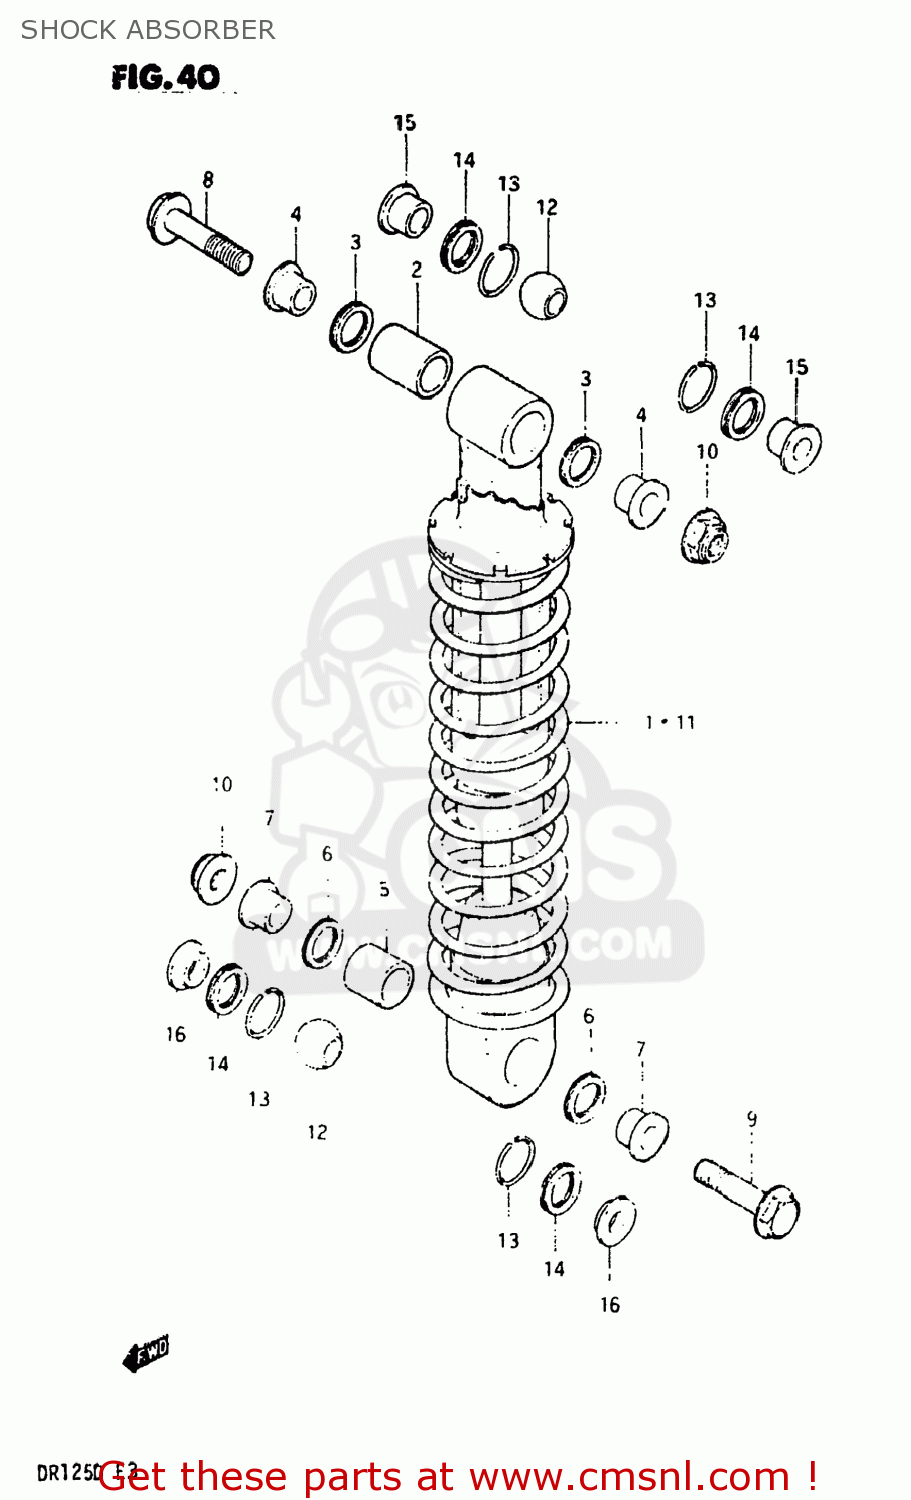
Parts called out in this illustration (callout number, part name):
1	ABSORBER ASSEMBLY,REAR SHOCK
2	BUSHING
3	DUST SEAL,LEVER CUSHION UNIT
4	BUSH,UPPER
5	BUSH,LEVER CUSHION UNIT
6	DUST SEAL,LEVER CUSHION UNIT
7	SPACER,LEVER CUSHION UNIT
8	BOLT(10X60)
9	BOLT(10X50)
10	NUT
11	ABSORBER ASSEMBLY,REAR SHOCK
12	BEARING,REAR SHOCK ABSORBER
13	RING
14	DUST SEAL
15	COLLAR,UPR
16	COLLAR,LWR
